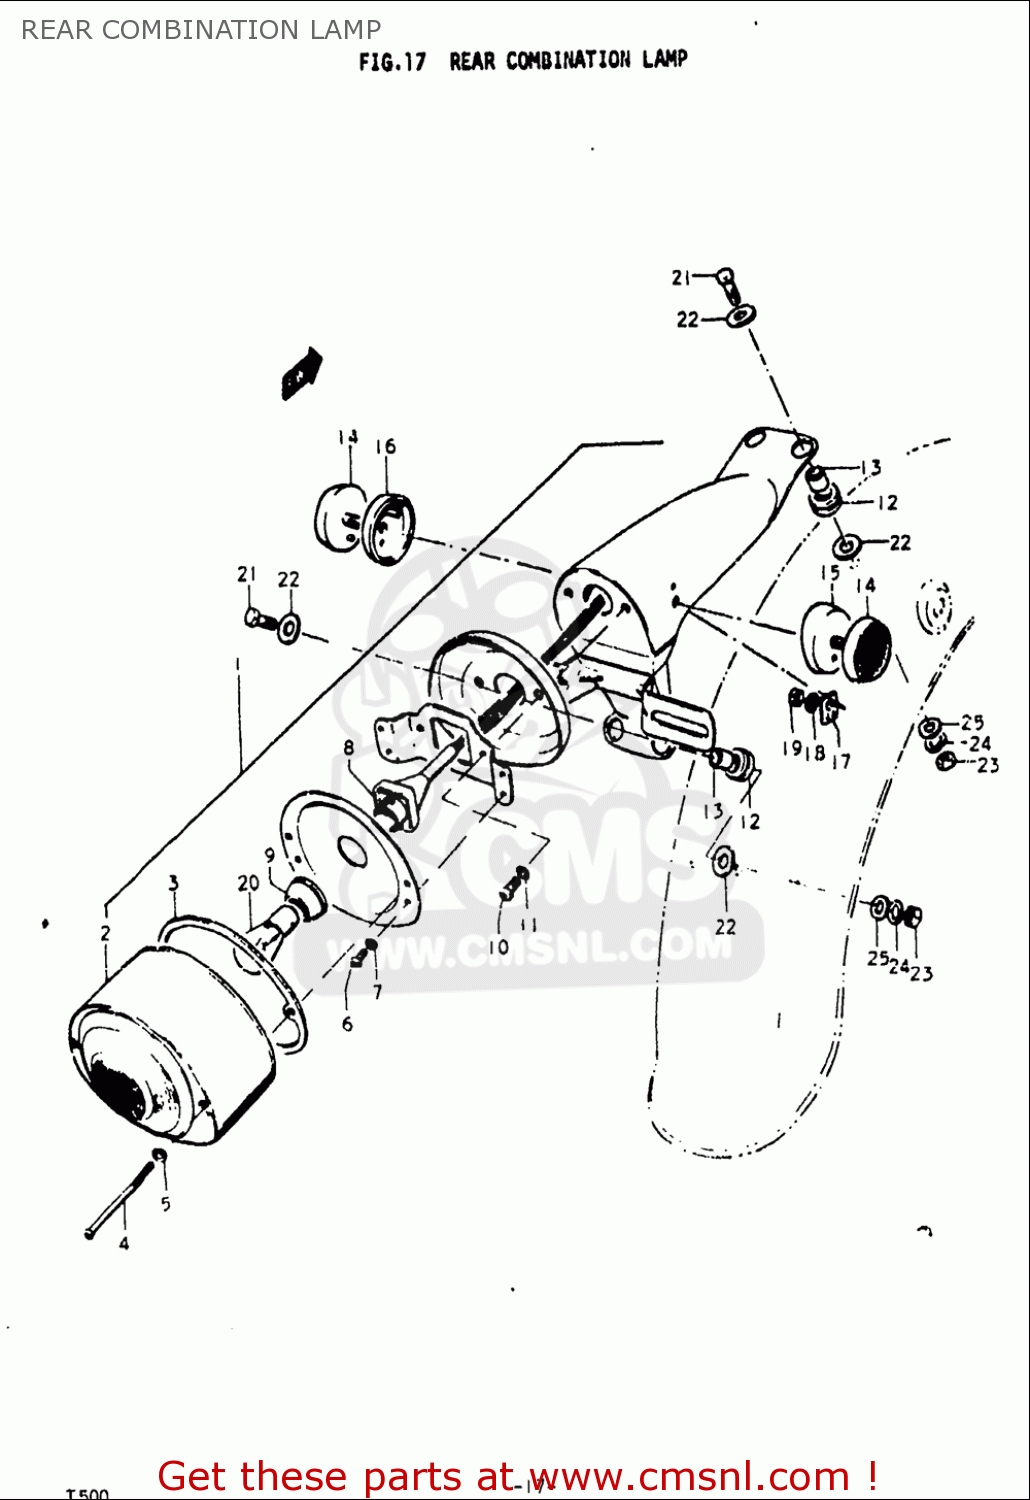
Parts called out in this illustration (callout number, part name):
2	LENS,RR COMBINATION LAMP
6	SCREW
7	WASHER,LOCK
10	SCREW
11	WASHER,LOCK
12	CUSHION
13	SPACER
18	WASHER,LOCK
19	NUT
20	BULB(12V23W)
21	BOLT 6X23
22	WASHER(6.5X20X1.6)
23	NUT
24	WASHER,LOCK
25	WASHER
